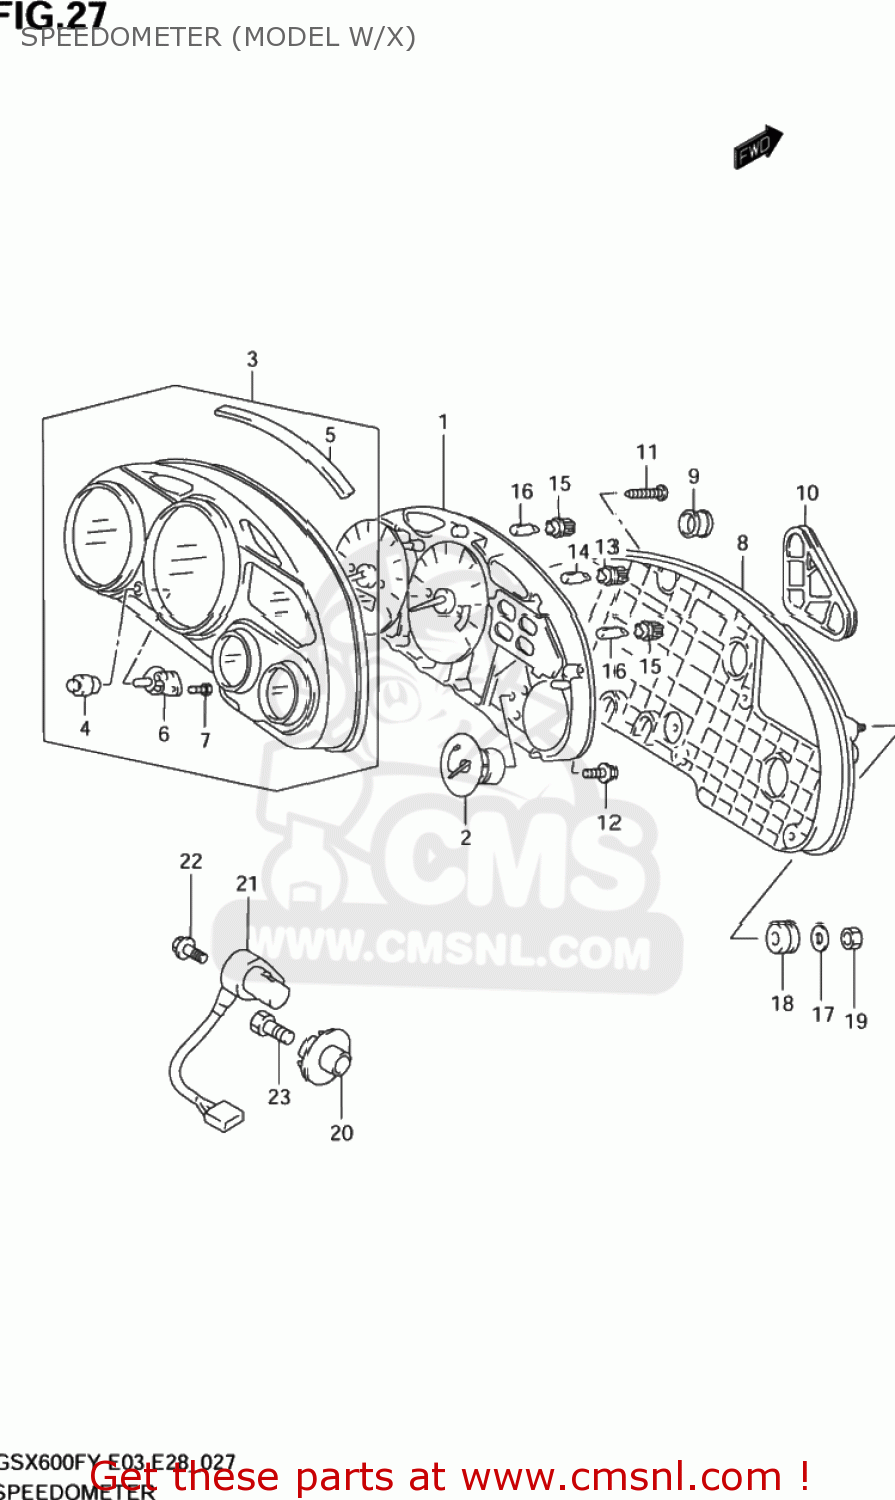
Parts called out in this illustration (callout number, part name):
1	SPEEDOMETER (KILO)
2	FUEL METER ASSEMBLY
3	VISOR ASSY
4	SWITCH,GUM
5	PACKING (NAS)
6	ATTACHMENT,SWITCH
7	SCREW(3X10)
8	CASE ASSY
9	CAP,BLIND NO.1
10	CAP,BLIND
11	SCREW
12	SCREW
13	SOCKET(T:6.5)
14	BULB(12V1.7W,T6.5)
15	SOCKET
16	BULB(14V1.4W,T5)
17	WASHER(6.5X22X1.6)
18	CUSHION
19	NUT 6MM
20	ROTOR,SPEED
21	SENSOR,SPEED
22	BOLT
23	BOLT
